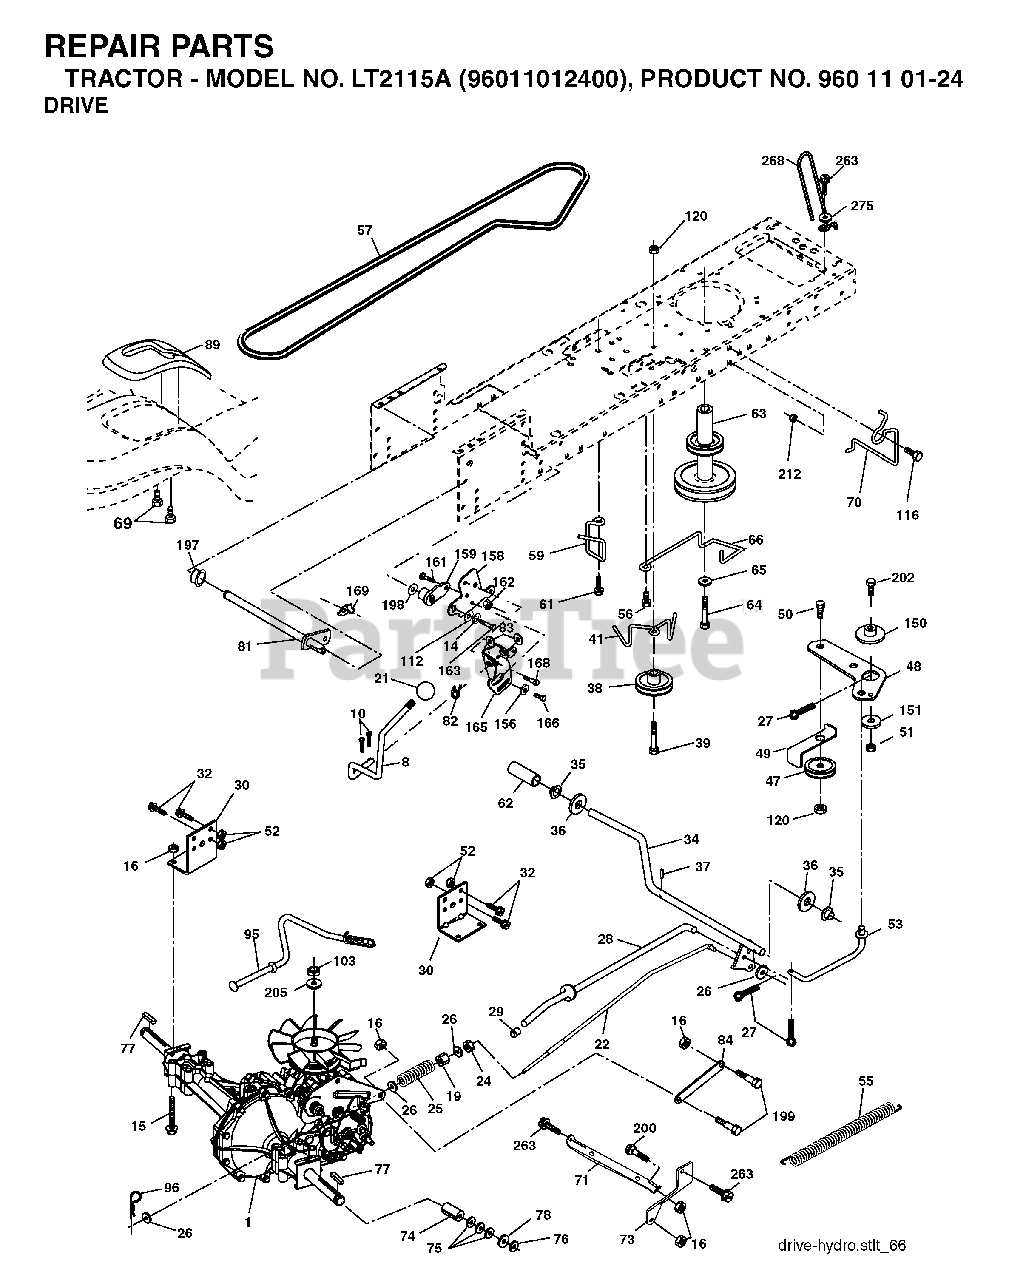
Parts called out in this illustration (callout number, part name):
8	ROD.SHIFT.FENDER.ADJ.STLT
10	PIN COTTER
14	LOCKWASHER
15	BOLT HEX 5/16-18 GR 5
16	NUT.71038.31-18.HEX.NYLOCK
19	NUT
21	KNOB.DUCKHEAD.1/2
22	ROD BRAKE HYDRO
24	NUT
25	SPRING ROD LT
27	COTTER PIN
28	ROD, PARKING BRAKE
29	PLUNGER CAP
30	BRKT, MOUNT TRNSAXLE
32	BOLT
34	SHAFT, FOOT PEDAL
35	BEARING.NYLON
36	WASHER LT
37	DRIVE PIN
38	PULLEY IDLER COMPOSITE
41	KEEPER, BELT IDLER
47	IDLER PULLEY
48	BELLCRANK, CLUTCH
49	RETAIN BELT
50	BOLT.3/8-16X1.50
51	LOCKNUT
52	LOCKNUT
53	LINK.CLUTCH.7.66.2005
55	SPRING, RETURN LT
56	SCREW.3/8-16
57	DRIVE BELT, LTH & YTH TRACTORS
59	KEEPER, BELT CENTER
61	SCREW 3/8-16X.875
62	PEDAL COVER T
63	ENGINE PULLEY
64	BOLT HEX 7/16-20X4-1/4"
65	LOCKWASHER
66	KEEPER BELT ENGINE
69	SCREW.HI-LO.CONSOLE
70	KEEPER BELT ENG
71	STRAP TORQUE LH HYDRO
73	STRAP TORQUE RH HYDRO
74	SPACER AXLE
76	E-RING LT
77	SQUARE KEY
81	SHAFT ASM CROSS TAPERED
82	SHIFT SPRING
83	WASHER
95	CONTROL ASM. BYPASS HYDRO
96	RETAINER M
103	NUT.HEX.1/2-20
112	WASHER LT
116	BOLT D
120	NUT LOCK FLG 3/8-16 UNC
150	SPACER, RETAINER
151	WASHER 12/32X2X10GA
156	WASHER.SRRTD.5/16
158	BRACKET
159	HUB.SHIFT
161	BOLT
162	NUT.CROWNLOCK.1/4
163	BOLT
165	RP BRACKET
166	SCREW
168	BOLT.SHOULDER.5/16-18X
169	PLATE.FASTENING.CROSS.SHAFT
197	NYLINER SNAP 5/8" ID
198	WASHER.NYL.7/8IDX.105"HYD CR
199	BOLT SHOULDER 5/16-18 UNC
200	BOLT
202	BOLT
205	WASHER
212	NUT
263	SCREW, 3/8-16X3/4
275	WASHER
